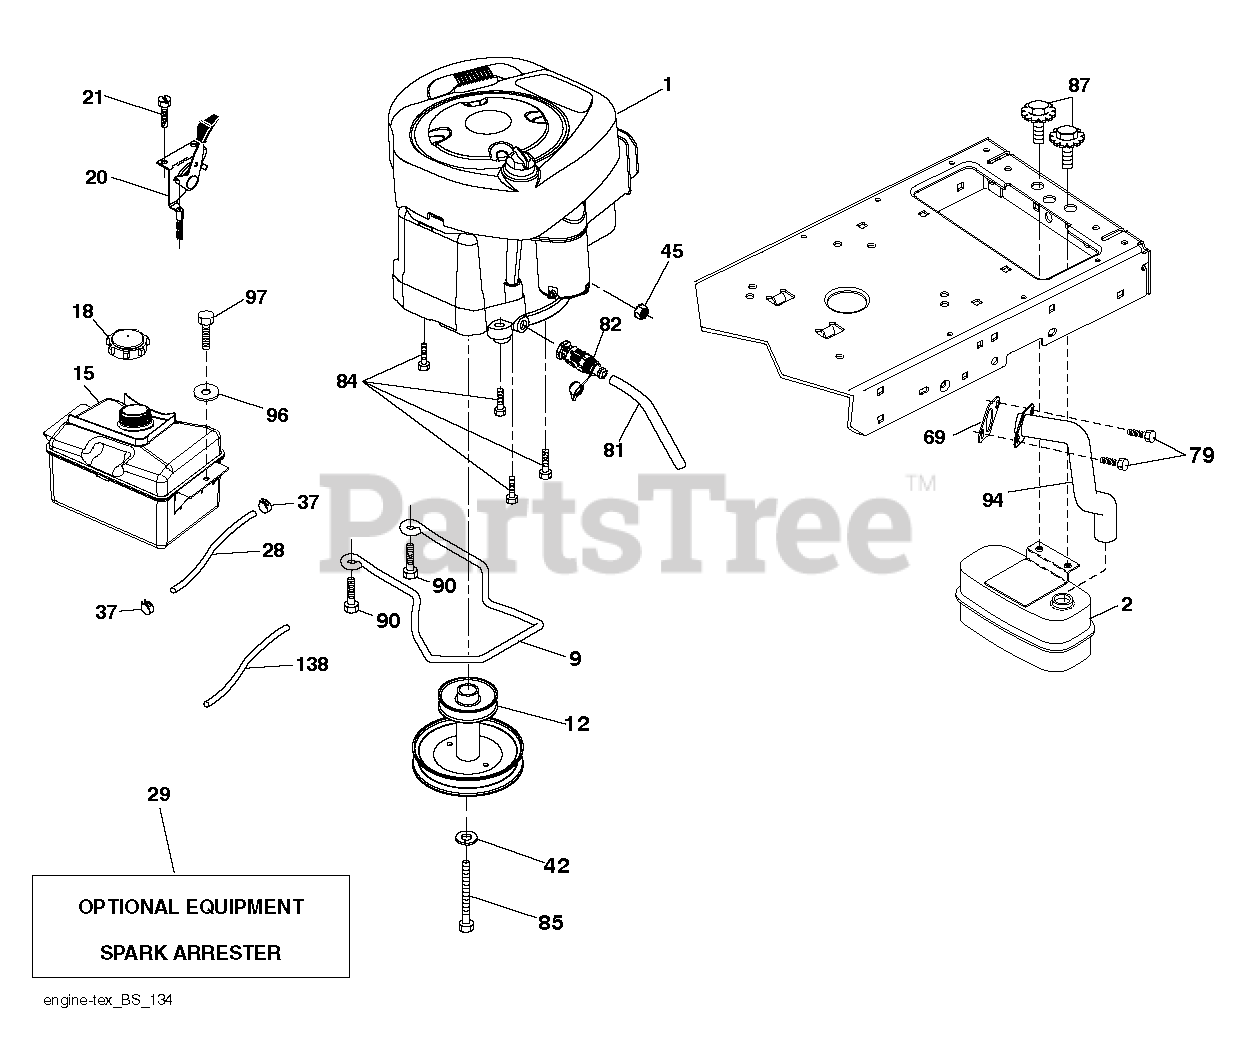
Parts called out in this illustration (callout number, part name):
2	MUFFLER.ASM.SNGL.XTNDED.DFLCTR
9	KEEPER.BELT.ENG.3.25"2BOLT.PNT
12	Engine Pulley
15	TANK ASSY TANK ASSY. 1.5 GAL.
18	CAP.FUEL.2 WAY VENT
20	THROTTLE.COBRA.21".RSTART.BLK
28	LINE.FUEL.20"FRONT.EMI
29	KIT.SPARK ARRESTOR(392390 B&S)
37	HOSE CLAMP
42	WASHER 7/16 LOCK
45	NUT
79	SCREW.SOCKET HD.5/16-1
81	TUBE, DRAIN OIL ASM.
82	VALUE.OIL.DRAIN
84	SCREW.3/8-16
85	Hex Bolt, 7/16-20 X 4-1/4" Grade 5
87	BOLT, 5/16-18 X 1 3/4
90	SCREW 3/8-16X1
94	Exhaust Tube, B&S 28/31
96	WASHER
97	SCREW HEXWSHR 1/4-20X3/4
138	RP PURGE LINE
